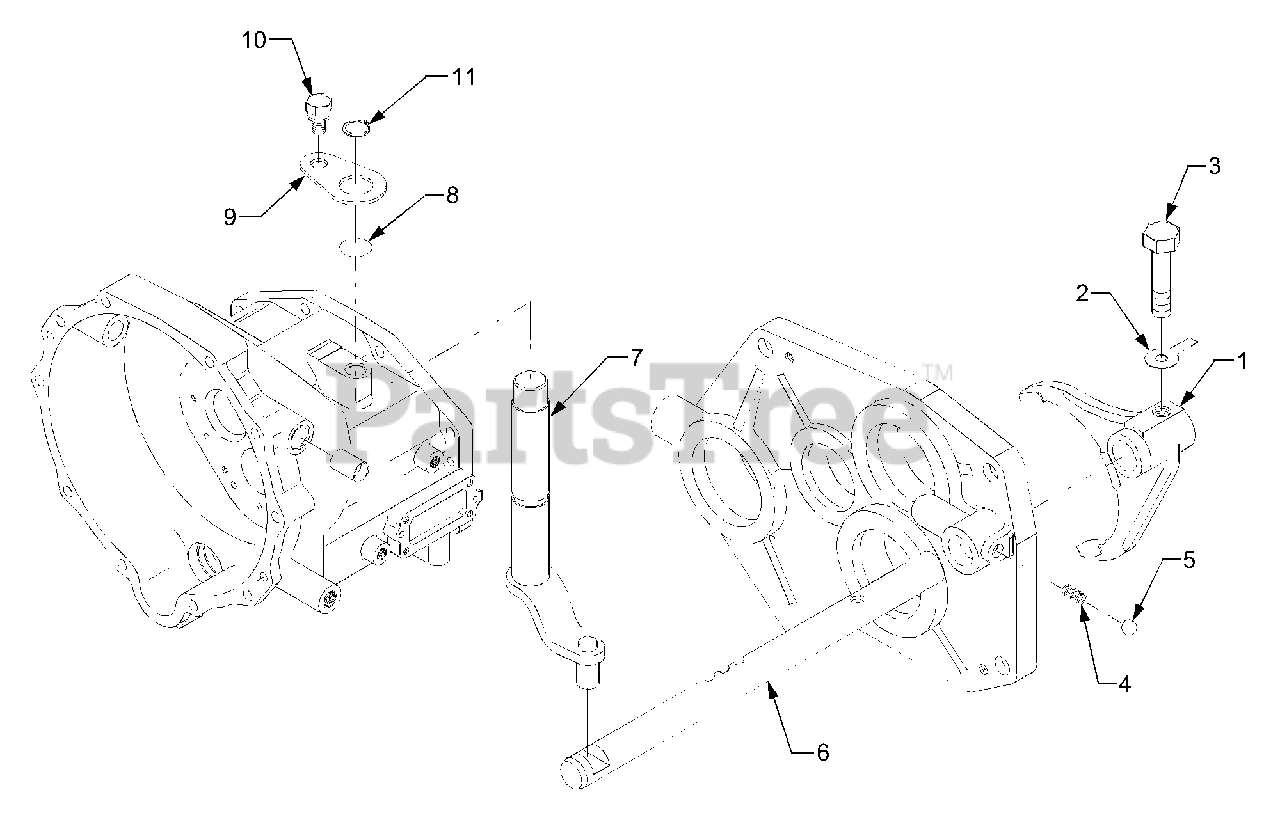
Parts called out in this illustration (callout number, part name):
1	Fork, Shift (Shuttle)
3	Bolt, Stopper
6	Rod, Fork (Shuttle)
7	Arm, Shift (Shuttle)
